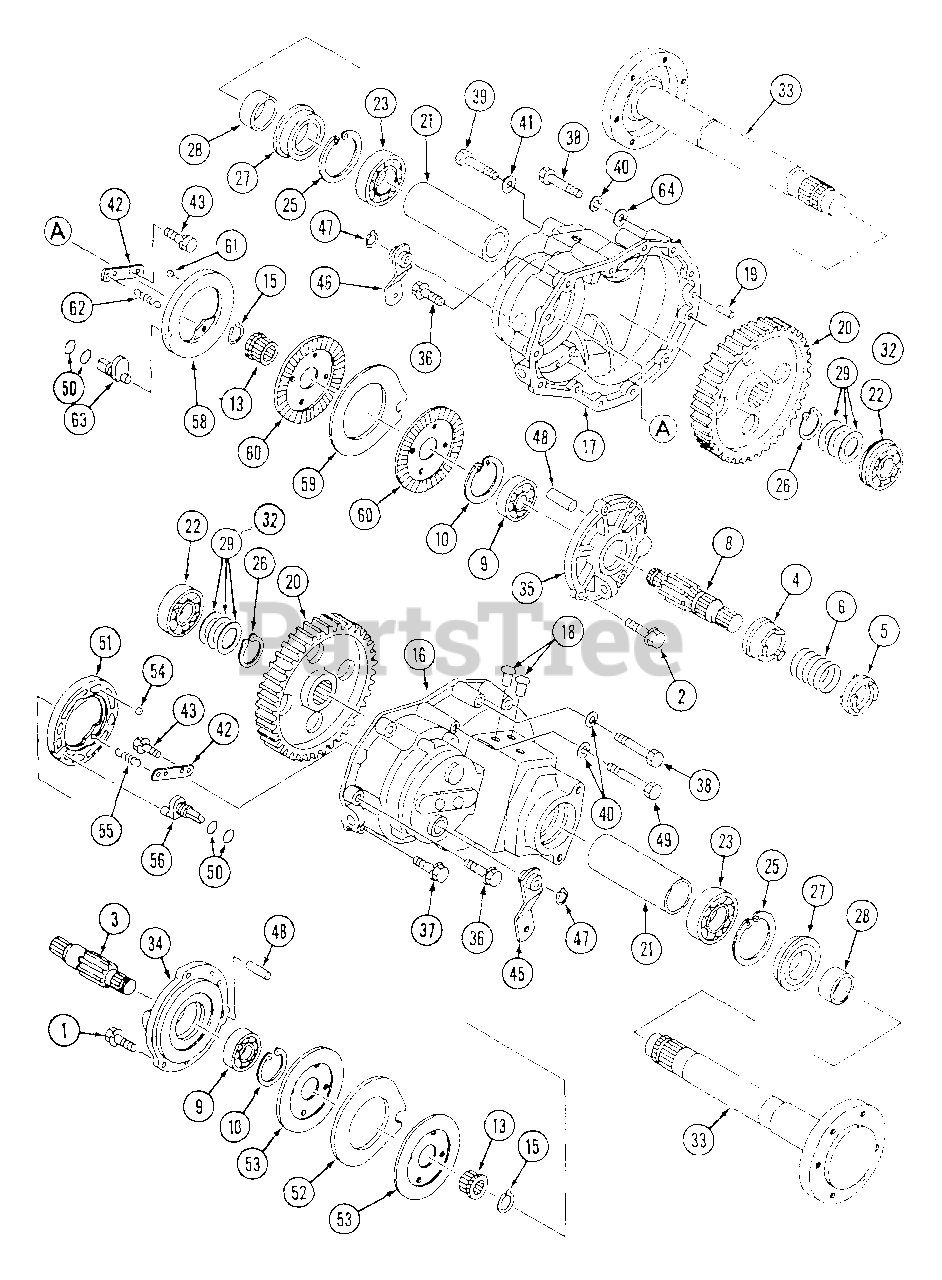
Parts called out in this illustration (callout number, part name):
16	Case L. H.
17	Case R. H.
29	Shim Set
45	Lever, Brake L.H.
46	Lever, Brake R.H.
52	Plate, Mating
55	Spring Return
59	Plate, Mating
62	Spring Return
